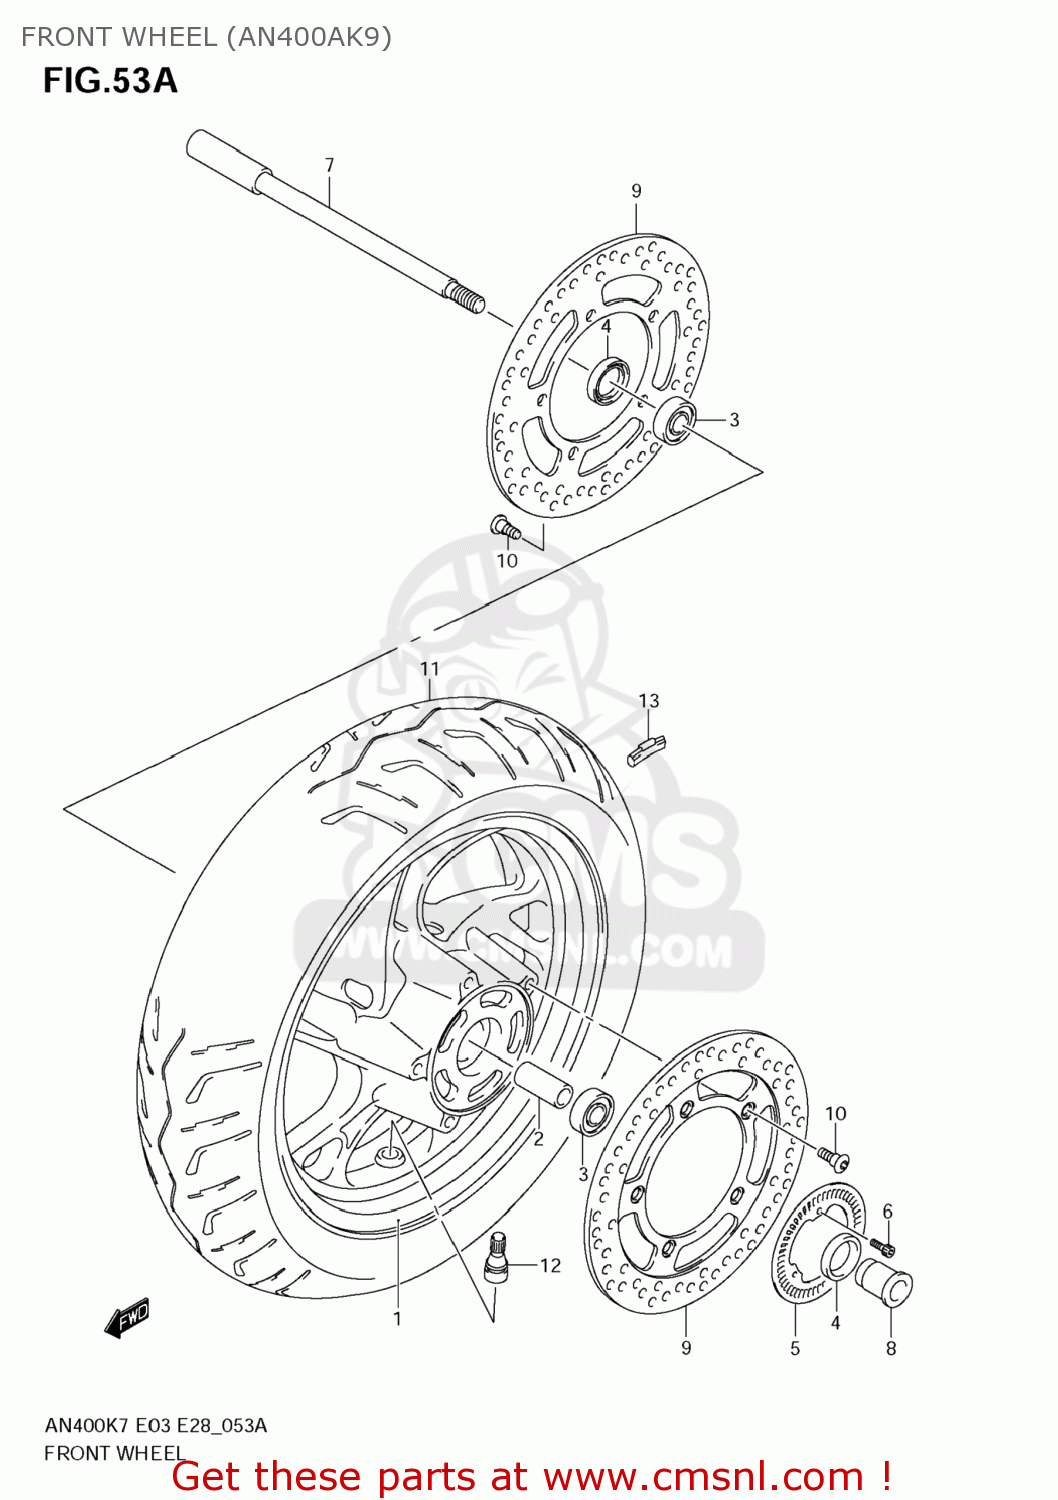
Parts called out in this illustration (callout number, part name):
1	WHEEL,FR(14M/CXMT3.00)
2	SPACER(15.3X21.7X100)
3	BEARING
4	SEAL,OIL(21X35X5)
5	RING,SPEED SENSOR FR(50T)
6	BOLT
7	AXLE,FR
8	SPACER,FR AXLE,L
9	DISC,FR BRAKE
10	BOLT(8X21)
11	TIRE,FR(120/80 14M/C 58S)
12	VALVE ASSY,WHEEL RIM(TR412)
13	WEIGHT,WHEEL BALANCE 10G
